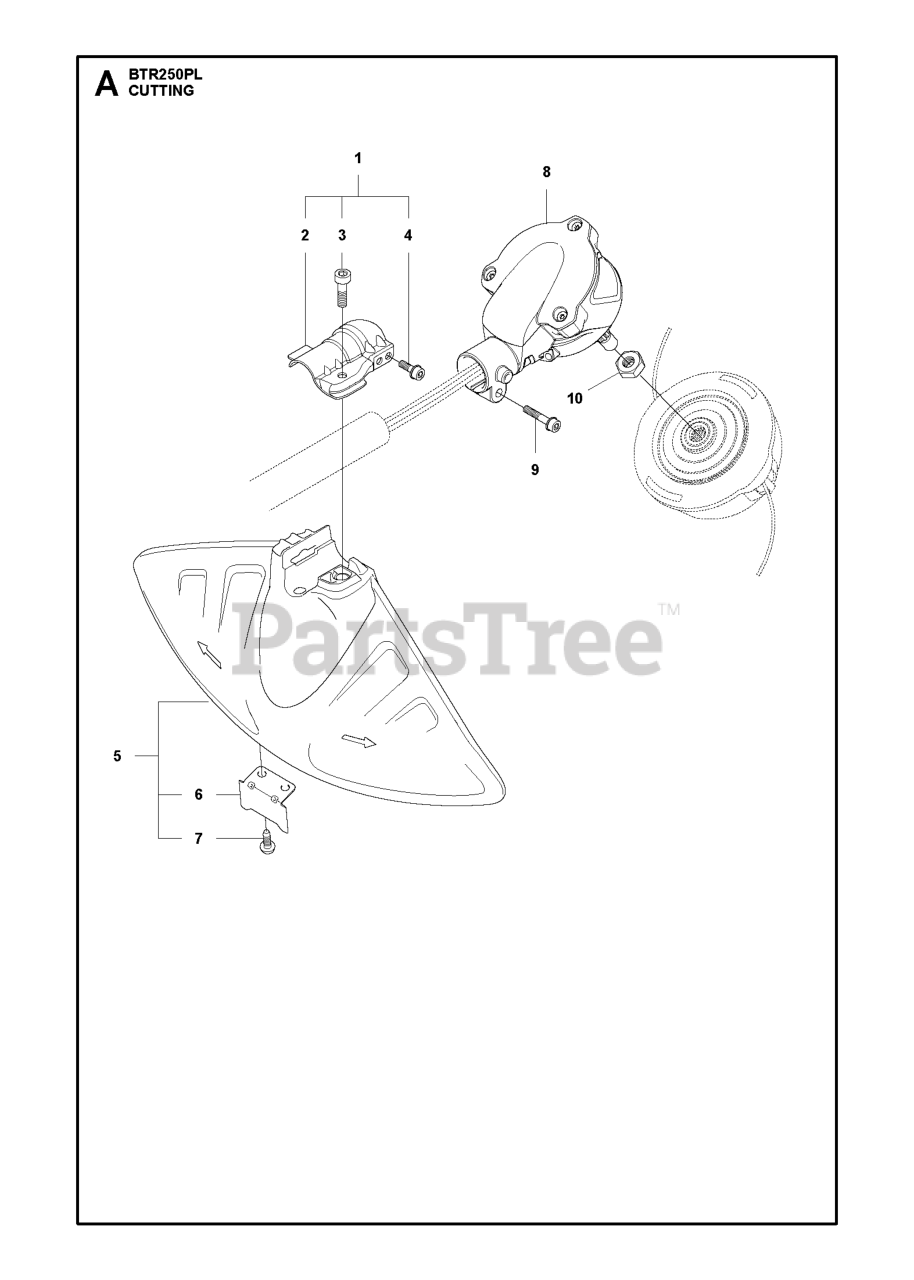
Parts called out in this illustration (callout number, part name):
2	RP BRACKET TRIMMER GUARD
3	SCREW IHSCM M6X22 10.9 ZN/FE
5	TRIMMER GUARD ASSY ZENOAH/REDM
6	LINE LIMITER
8	MOTOR ASSY BLDC ZENOAH/REDMAX
10	GEARHEAD NUT - BRUSHCUTTER
